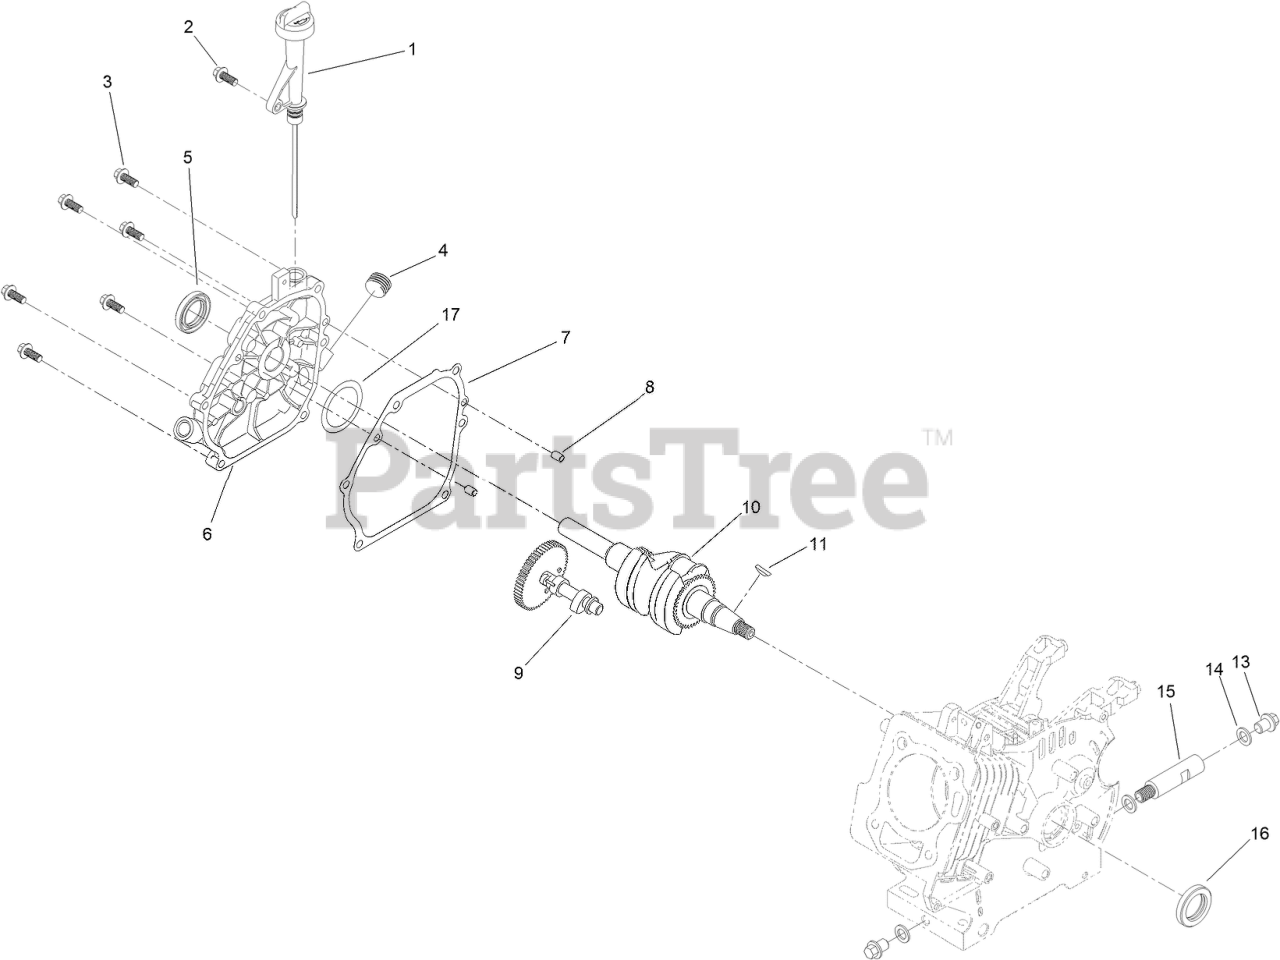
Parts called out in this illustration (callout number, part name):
1	OIL FILL ASSEMBLY
2	SCREW-HHF
3	SCREW-HHF
4	Plug-Drain
5	SEAL-OIL
6	COVER-CRANKCASE
7	GASKET-COVER, CRANKCASE
8	PIN-DOWEL
9	CAMSHAFT ASM
10	CRANKSHAFT
11	KEY-WOODRUFF
13	SCREW-HHF
14	WASHER-PLAIN
15	TUBE-DRAIN, OIL
16	SEAL-OIL
17	WASHER-THRUST
